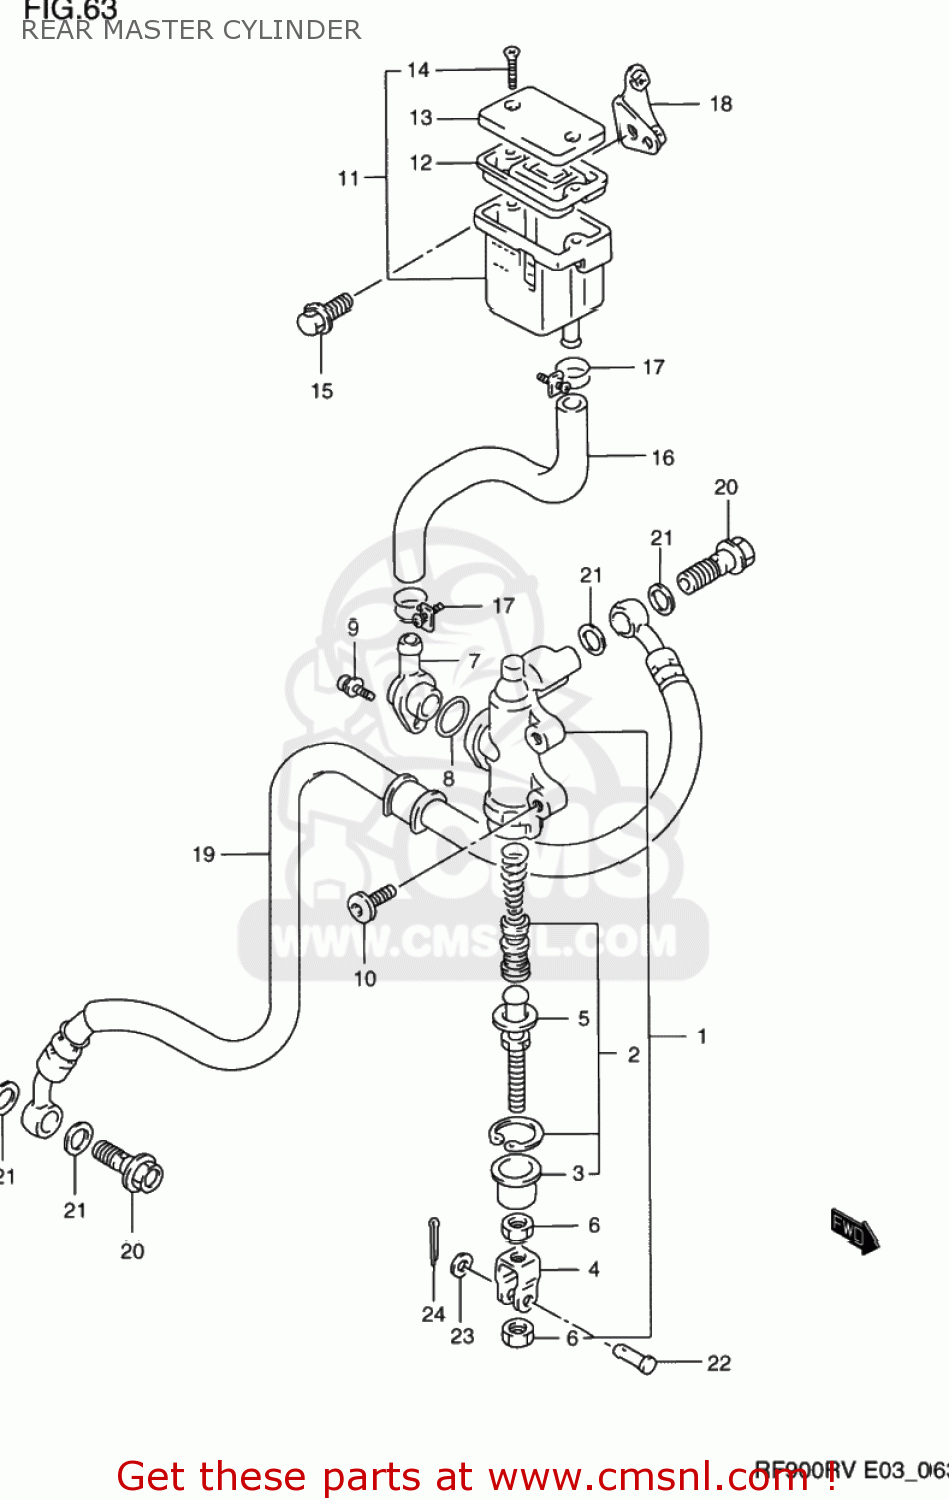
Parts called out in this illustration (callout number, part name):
1	CYLINDER ASSY,RR MASTER
2	PISTON/CUP SET
3	BOOT
4	YOKE
5	ROD,PUSH
6	NUT
7	CONNECTOR
8	O RING
9	SCREW
10	BOLT 8X20
11	TANK ASSY,RESERVOIR
12	DIAPHRAGM
13	CAP
14	SCREW
15	BOLT
16	HOSE,RESERVOIR TANK
17	CLIP
18	PLATE COMP,RESERVOIR T
19	HOSE,RR BRAKE
20	BOLT UNION
21	WASHER(10X15X1.5)
22	PIN
23	WASHER
24	PIN
